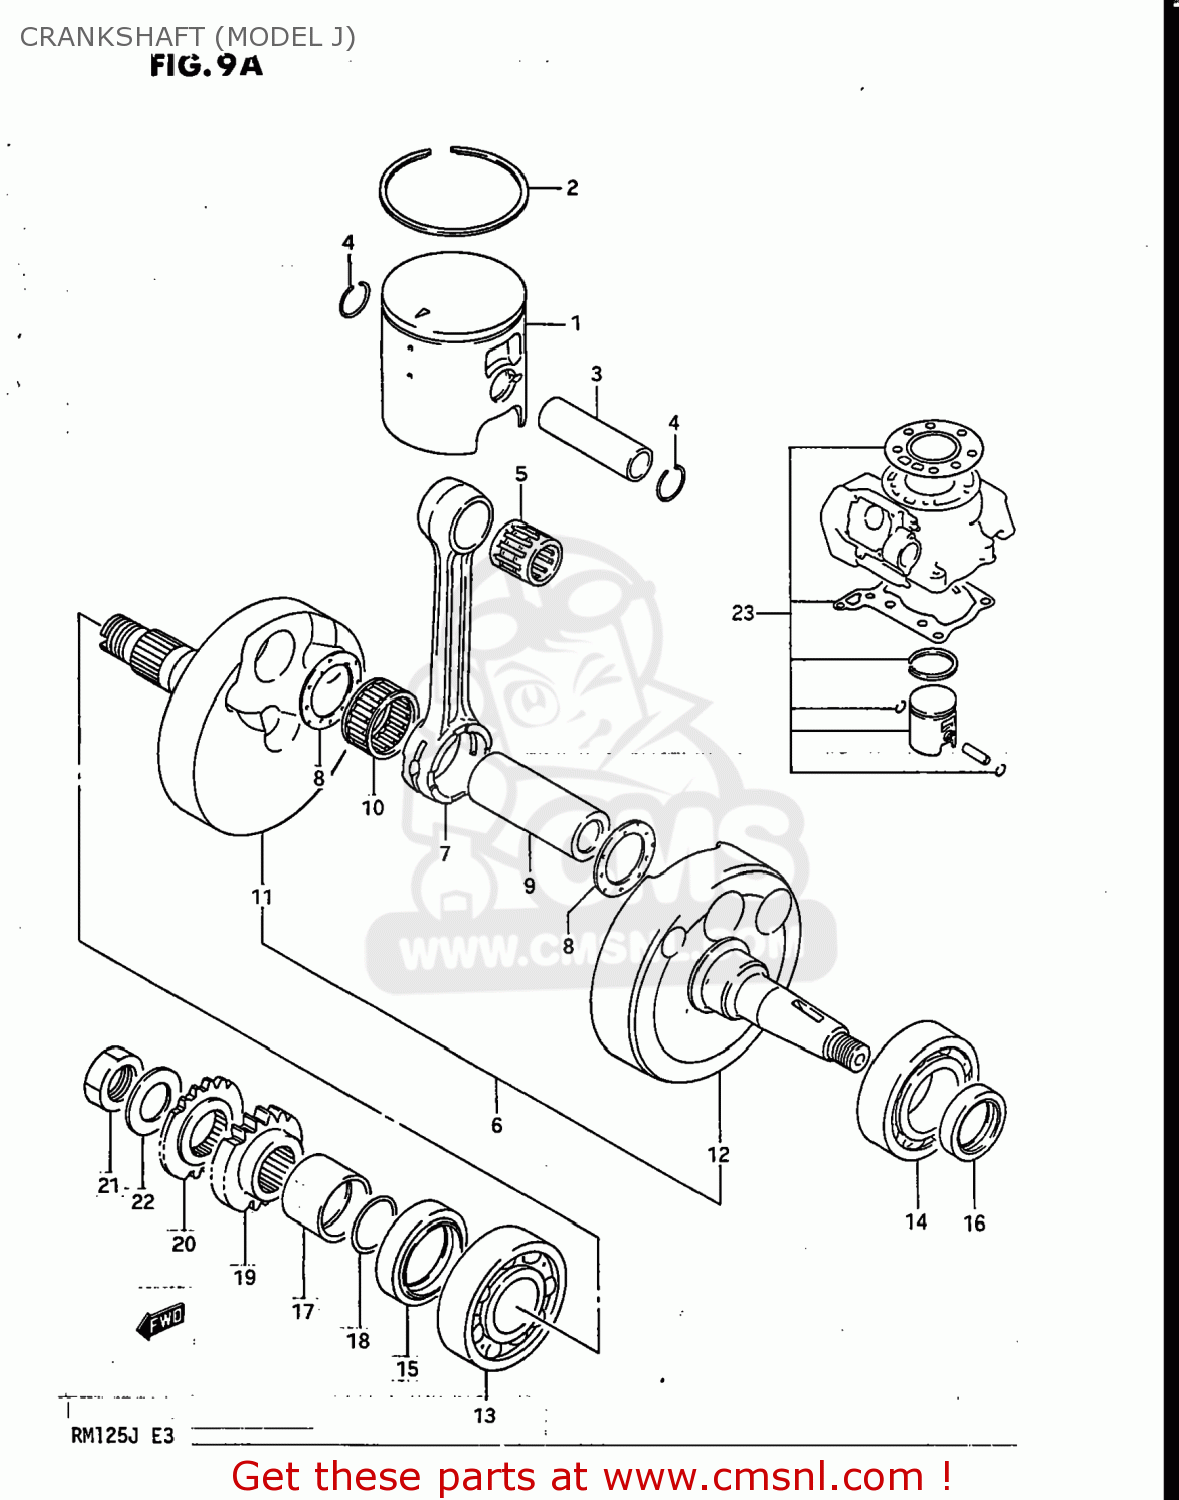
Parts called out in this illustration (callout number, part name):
1	PISTON
2	RING,PISTON
3	PIN,PISTON
4	CIRCLIP
5	BEARING(15X19X20)
6	CRANKSHAFT ASSEMBLY
7	CONNECTING ROD
8	WASHER(22X35X1)
9	PIN,CRANK
10	BEARING(22X28X16)
11	CRANKSHAFT,RIGHT
12	CRANKSHAFT,LEFT
13	BEARING
14	BEARING(25X52X15)
15	SEAL,OIL(28X40X8)
16	SEAL,OIL(18X30X6)
17	SPACER,PRIMARY DRIVE GEAR
18	O RING(D:2.4,ID:19.8)
19	GEAR,PRIMARY DRIVEN
20	GEAR, GOVERNOR DRIVE (NT:19)
21	NUT
22	WASHER
23	PISTON KIT (STD)
